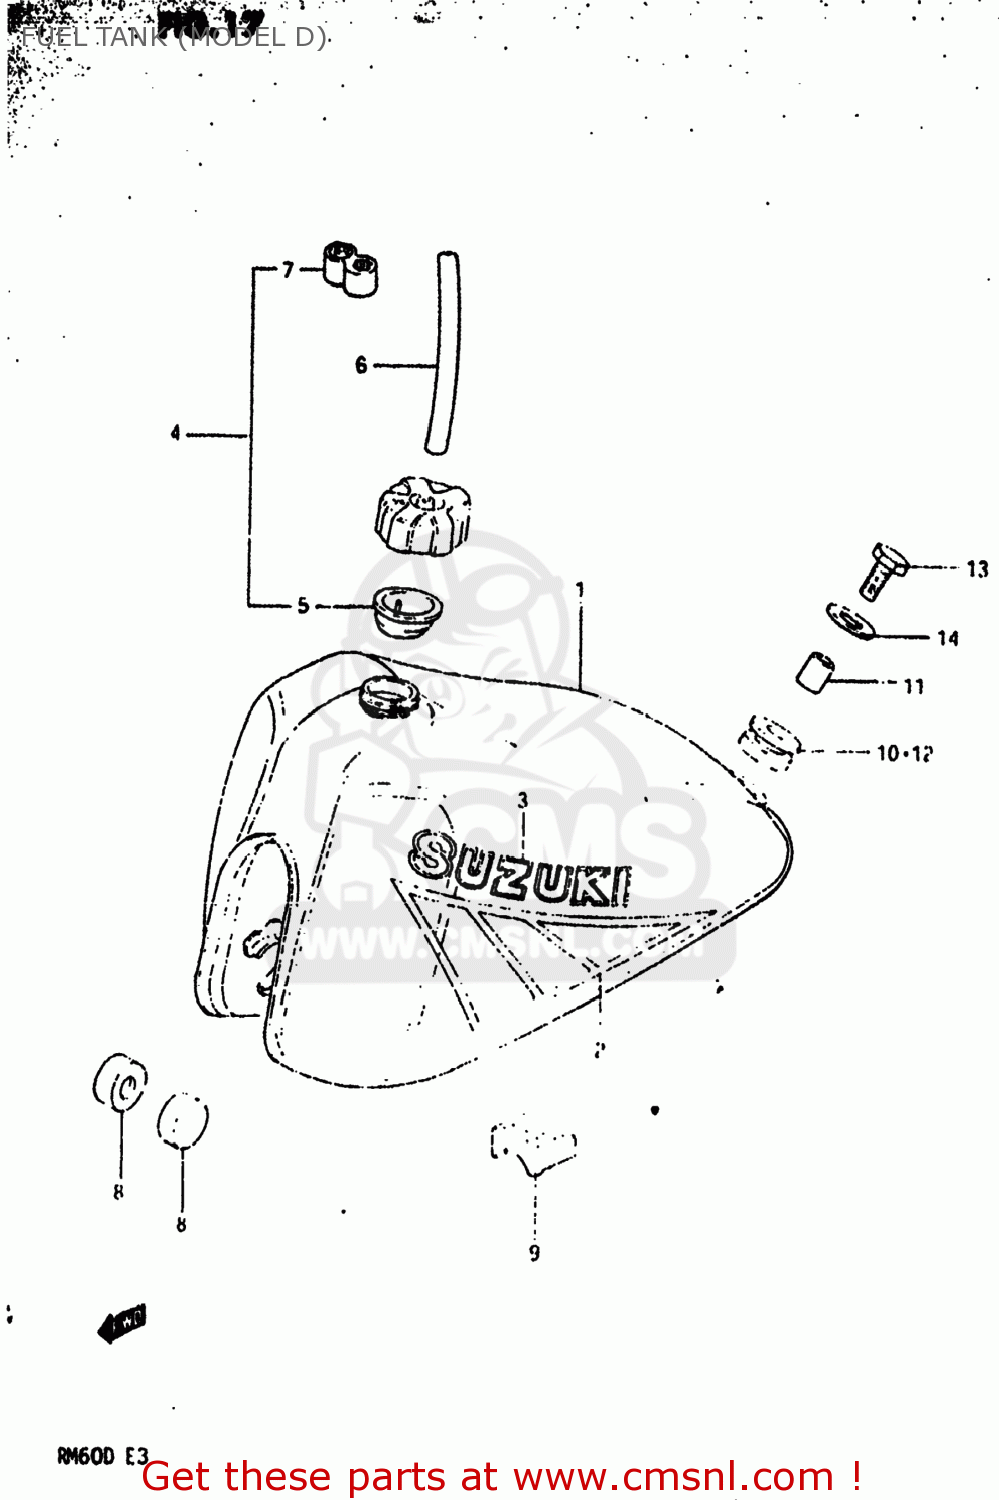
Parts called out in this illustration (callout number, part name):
1	TANK ASSEMBLY,FUEL
2	TAPE SET,FUEL TANK
3	EMBLEM
4	CAP ASSEMBLY,FUEL TANK
5	GASKET,FUEL TANK CAP
6	HOSE
7	CLAMP,FUEL TANK BREATHER HOSE
8	CUSHION
9	CUSHION,FUEL TANK
10	CUSHION
11	SPACER (8.8X12X13.5)
12	CUSHION
13	BOLT
14	WASHER (8.5X29X1.6)
